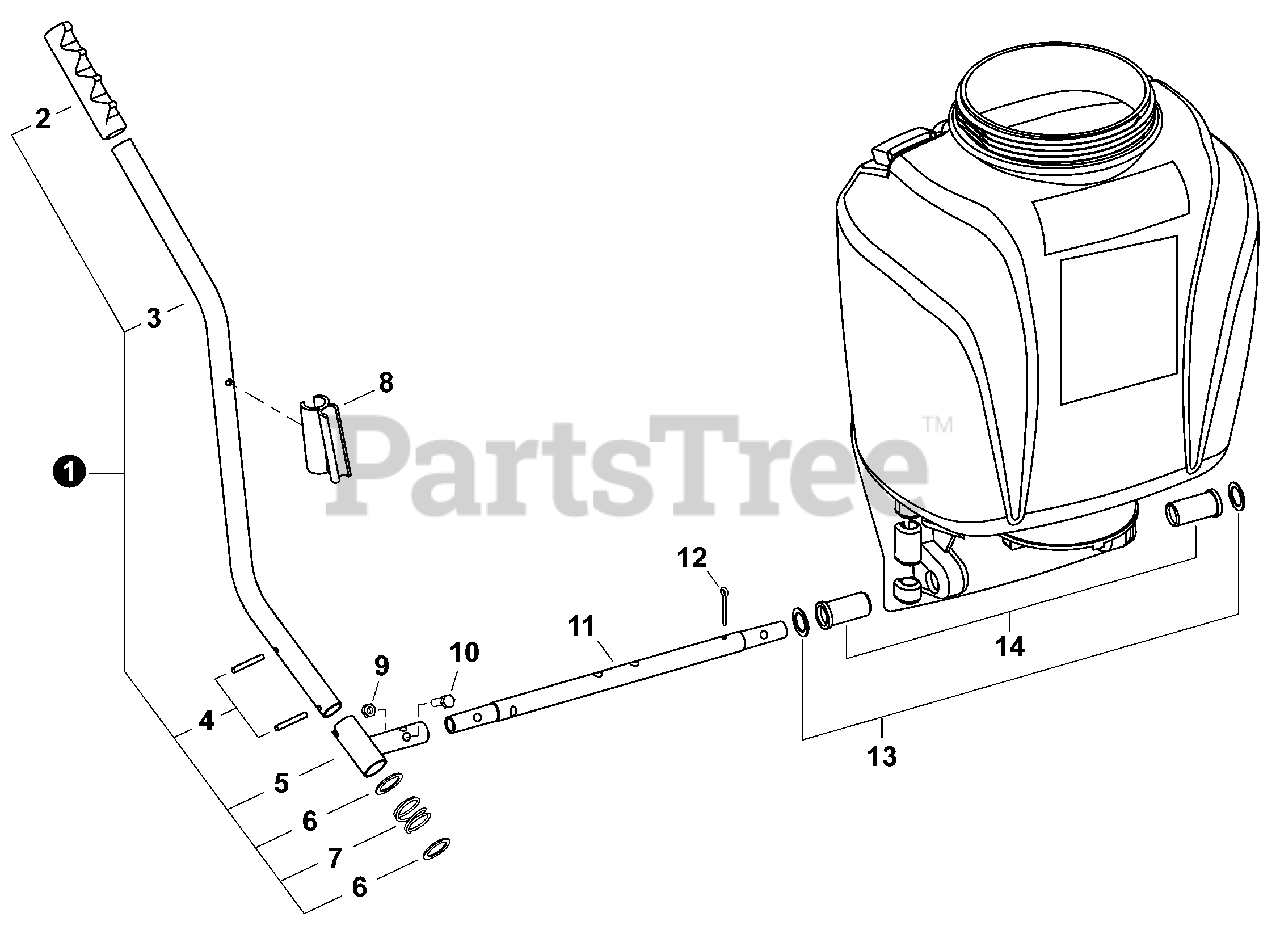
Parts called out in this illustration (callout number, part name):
1	LEVER KIT, PUMP
2	GRIP, LEVER
3	LEVER, PUMP
4	PIN, LEVER
5	BRACKET, LEVER
6	WASHER, LEVER
7	SPRING, LEVER
8	CLIP, WAND
9	NUT M6
10	BOLT M6×20
11	SHAFT, PUMP
12	PIN, SHAFT
13	WASHER, SHAFT
14	BUSHING, SHAFT
